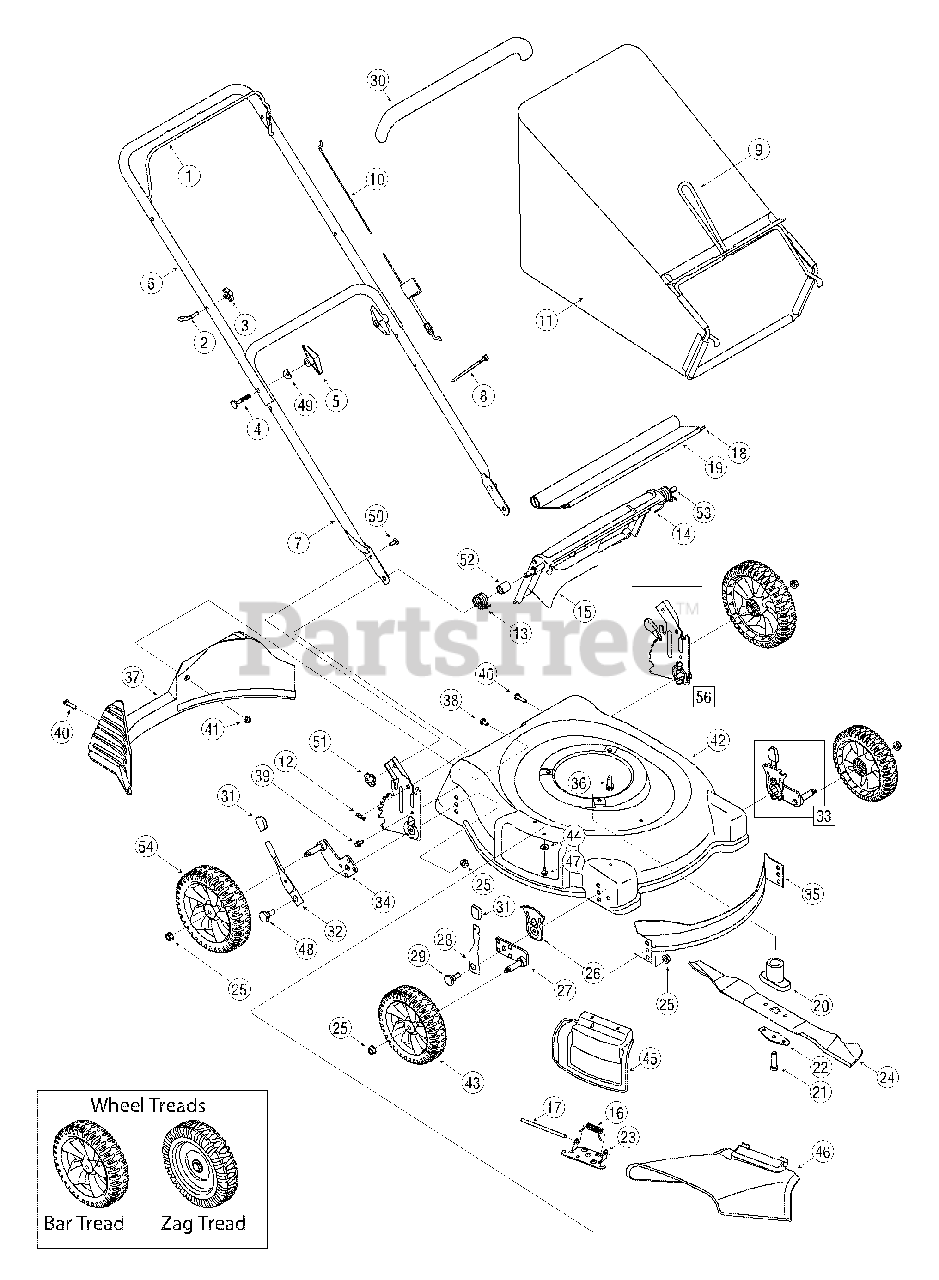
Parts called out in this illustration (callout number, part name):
2	Rope Guide
3	Handle Knob 1/4-20 Thd.
4	Curved Hd. Bolt 5/16-18 x 2"
5	Hand Knob
8	Cable Tie
10	Control Cable - 37.25"
11	Grass Bag
12	Int. Cotter Pin 5/16" Dia.
13	Door Spring - R.H.
14	Door Spring - L.H.
15	Rear Discharge Door
16	Torsion Spring
17	Hinge Pin
18	Wire Rod
19	Rear Flap
20	Blade Adapter w/Star
21	Hex Bolt 3/8-24 x 2.5" Lg.
22	Blade Bell Support
23	Deflector Chute Adapter
24	21" Mulching Blade w/Star
25	Flange Nut 3/8-16 Thd.
26	Height Adj. Plate
27	Pivot Arm Assembly - RH (8" Wheels)
28	Front Spring Lever
29	Shld. Bolt.5" Dia. x.357"
30	Deluxe Bail Cover
31	Spring Lever Knob
32	Rear Spring Lever
33	Height Adj. Assy. Comp. - RH (8" Whl)
34	Pivot Arm R.H.
35	Front Baffle
36	Hex L-Wash.Scr. 3/8-16 x 1"
37	Rear Baffle
38	Screw, 1/4-20 x.500"
39	Hex Ind Wash. Scr. 1/4-20:.625
40	Screw, 1/4-15 x 1.250
41	Flange Lock Nut, 1/4-20
44	Bell Washer 1/4" I.D.
45	Hinged Mulching Plug
46	Side Chute Deflector
47	Hex Hd Self-Tp Scr. 1/4-20 x.5"
48	Shoulder Screw
49	Shoulder Washer
50	Hex Carriage Screw 1/4-20
51	Wing Nut
52	Spacer,.375OD x.50ID
53	Rear Door Pivot Rod
54	Rear Wheel
56	Rear Handle Bracket Assembly - LH
